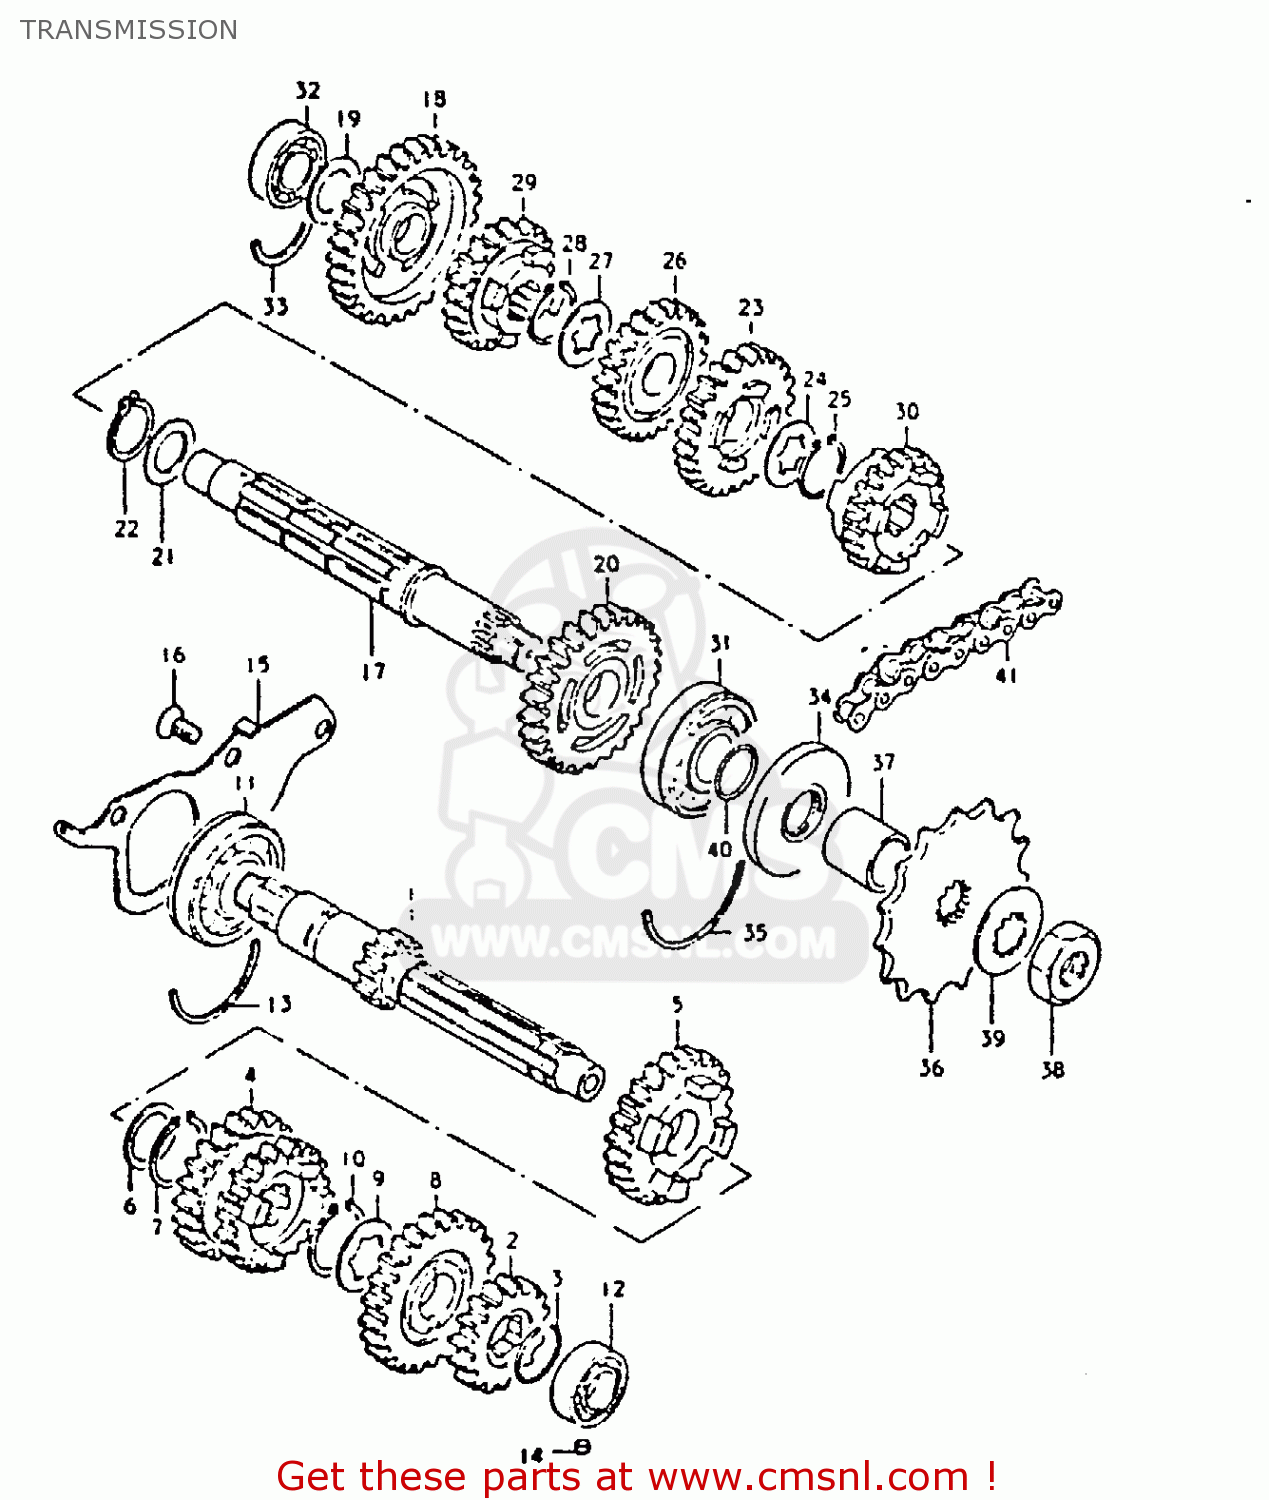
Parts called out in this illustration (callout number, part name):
1	SHAFT,COUNTER
2	GEAR,SECOND DRIVE
3	CIRCLIP
4	GEAR,THIRD/FOURTH DRIVE
5	GEAR,FIFTH DRIVE
6	SHIM
7	CIRCLIP
8	GEAR,SIXTH DRIVE
9	WASHER,LOCK
10	CIRCLIP
11	BEARING
12	ROLLER BEARING (17X31X1
13	C RING
14	PIN
15	RETAINER,BEARING
16	SCREW
17	SHAFT,DRIVE
18	GEAR,FIRST DRIVEN
19	WASHER,THRUST
20	GEAR,SECOND DRIVEN
21	SHIM
22	CIRCLIP
23	GEAR,THIRD DRIVEN
24	WASHER,LOCK
25	CIRCLIP
26	GEAR,FOURTH DRIVEN
27	WASHER,LOCK
28	CIRCLIP
29	GEAR,FIFTH DRIVEN
30	GEAR,SIXTH DRIVEN
31	BEARING
32	BEARING, RH
33	C RING
34	SEAL,OIL(25X52X11.5)
35	C RING
36	SPROCKET,ENGINE(NT:15)
37	SPACER
38	NUT
39	WASHER,LOCK
40	O RING(D:1,ID:19.5)
41	CHAIN ASSEMBLY,DRIVE
